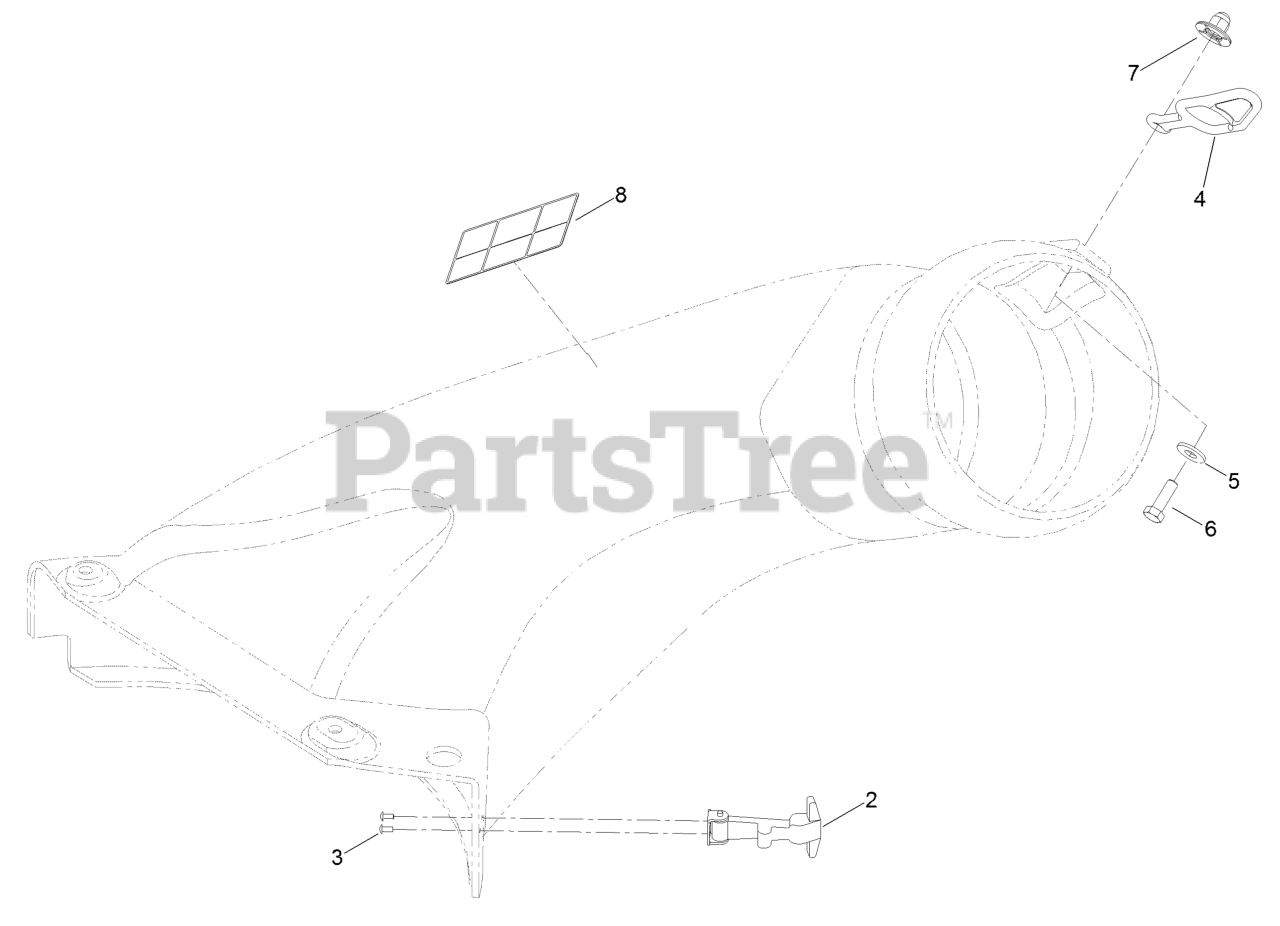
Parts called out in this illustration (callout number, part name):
2	HANDLE ASM
3	RIVET-POP
4	RETAINER-DUCT
5	WASHER-FLAT
6	SCREW-HH
7	NUT-IMPELLER
8	DECAL-DANGER
